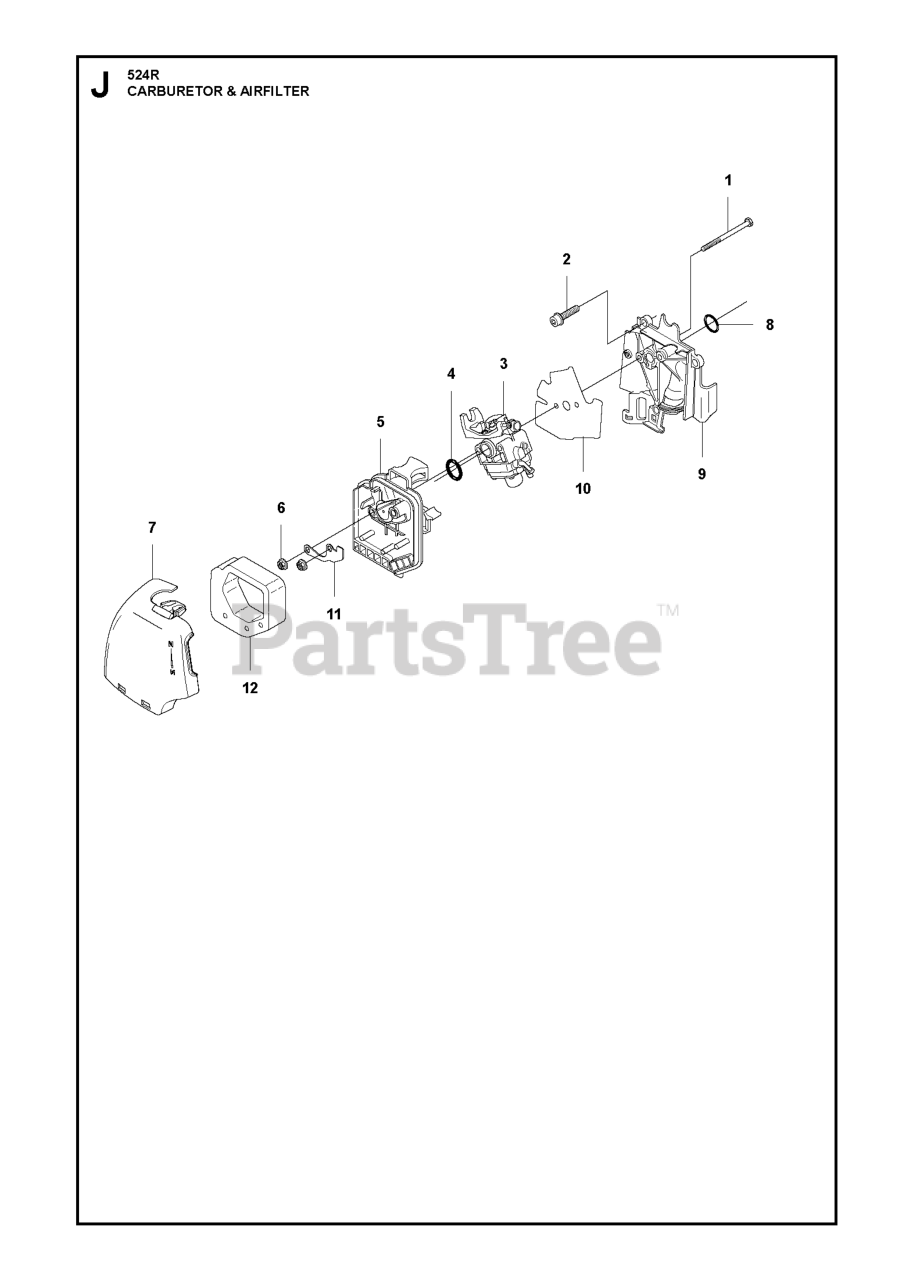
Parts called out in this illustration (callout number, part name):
3	CARBURETOR
7	COVER, AIR CLEANER
12	AIR FILTER
